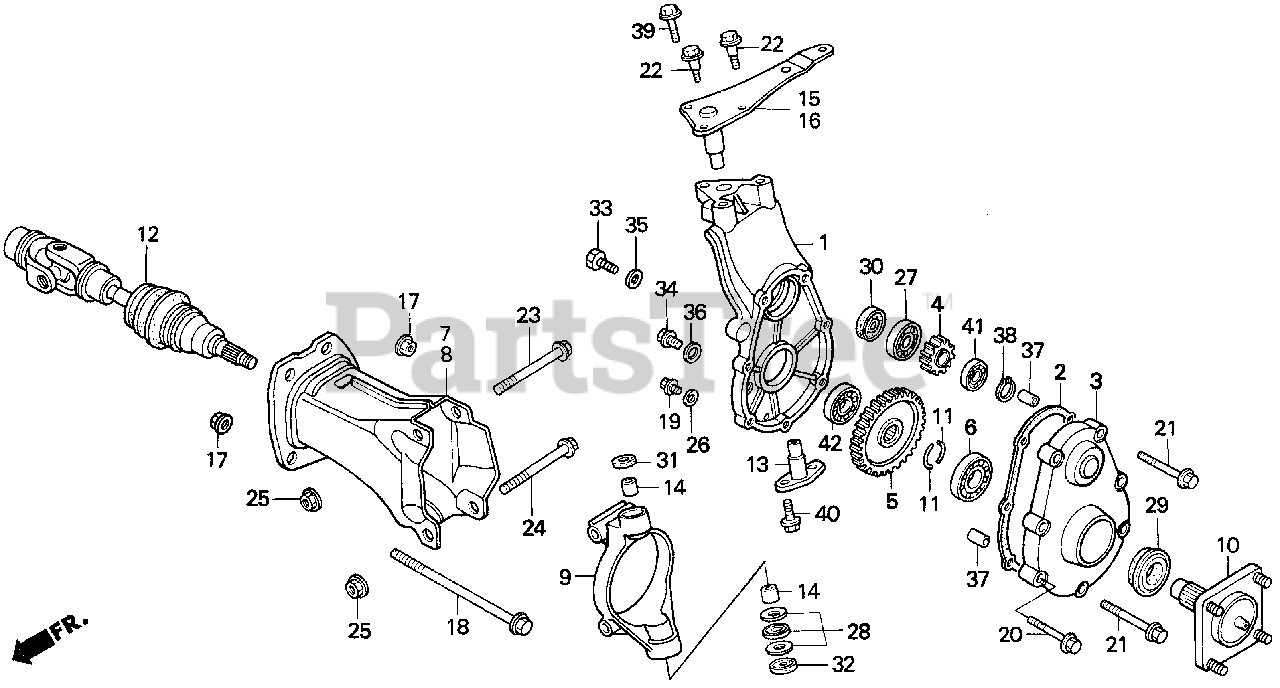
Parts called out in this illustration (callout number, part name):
1	CASE, FINAL REDUCTION
2	GASKET, FINAL REDUCTION
3	COVER, FINAL REDUCTION
4	GEAR, FR. FINAL DRIVE
5	GEAR, FR. FINAL DRIVEN
6	BEARING, RADIAL BALL SPECIAL (6206)
7	TUBE, R. FR. AXLE
8	TUBE, L. FR. AXLE
9	HOLDER, FINAL REDUCTION CASE
10	SHAFT, AXLE
11	KEY, AXLE SHAFT LOCK
12	JOINT ASSY., FR. DRIVE
13	KINGPIN (LOWER)
14	BUSH, KINGPIN
15	ARM, R. FR. KNUCKLE
16	ARM, L. FR. KNUCKLE
17	NUT, SELF-LOCK (10MM)
18	BOLT, HEX. (10X144)
19	BOLT, SEALING (8MM)
20	BOLT, UBS (8X36)
21	BOLT, KNOCK (8X46)
22	BOLT, KNOCK (10X32)
23	BOLT, FLANGE (12X105)
24	BOLT, FLANGE (12X125)
25	NUT, SELF-LOCK (12MM) (SATO RASHI)
26	WASHER (8MM)
27	BEARING, RADIAL BALL (62/22)
28	BEARING, THRUST (17X30X9)
29	SEAL, WATER (32X52X11) (NOK)
29	SEAL, WATER (32X52X10.5) (NOK)
30	OIL SEAL (24X42X7) (ARAI)
31	OIL SEAL (22X35X8)
32	OIL SEAL (25X38X8)
33	BOLT, HEX. (8X12)
34	BOLT, DRAIN PLUG (14MM)
35	WASHER, PLAIN (8MM)
36	WASHER, DRAIN PLUG (14MM)
37	PIN A, DOWEL (10X16)
38	CIRCLIP (OUTER) (17MM)
39	BOLT, FLANGE (10X25)
40	BOLT, FLANGE (10X28)
41	BEARING, RADIAL BALL (6203)
42	BEARING, RADIAL BALL (6205)
